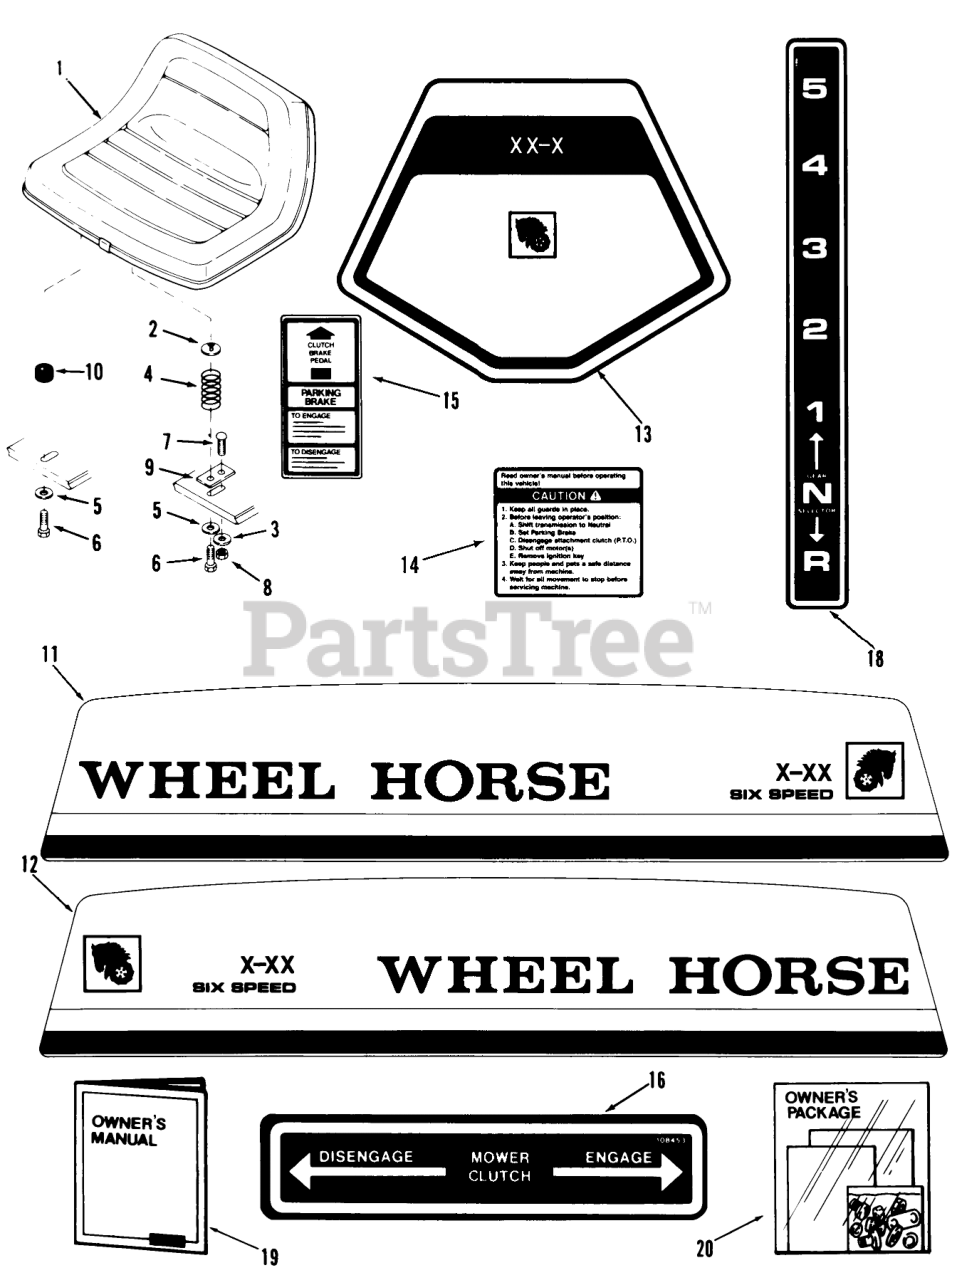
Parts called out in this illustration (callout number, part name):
1	ASSY-SEAT
2	NUT-PUSH
3	Washer
4	SPRING
5	WASHER 5/16 SAE
6	SPECIAL BOLT
6	HHCS
7	CARRIAGE BOLT -4
8	Nut
9	Plate Seat
10	GROMMET-RUBBER
11	Decal-Hood A-81 RH
11	DECAL-SIDE A-111
12	Decal-Hood A-81 LH
12	Rubber Plate
13	Decal-Shroud A-81
13	Decal-Shroud A-111
14	DECAL-CAUTION
15	Decal-Parking Brake
16	Decal-PTO
18	DECAL-SHIFT
19	Owner-s Manual (Rider)
20	New Rider Loose Parts Pkg A-81
20	New Rider Loose Parts Pkg A-111
